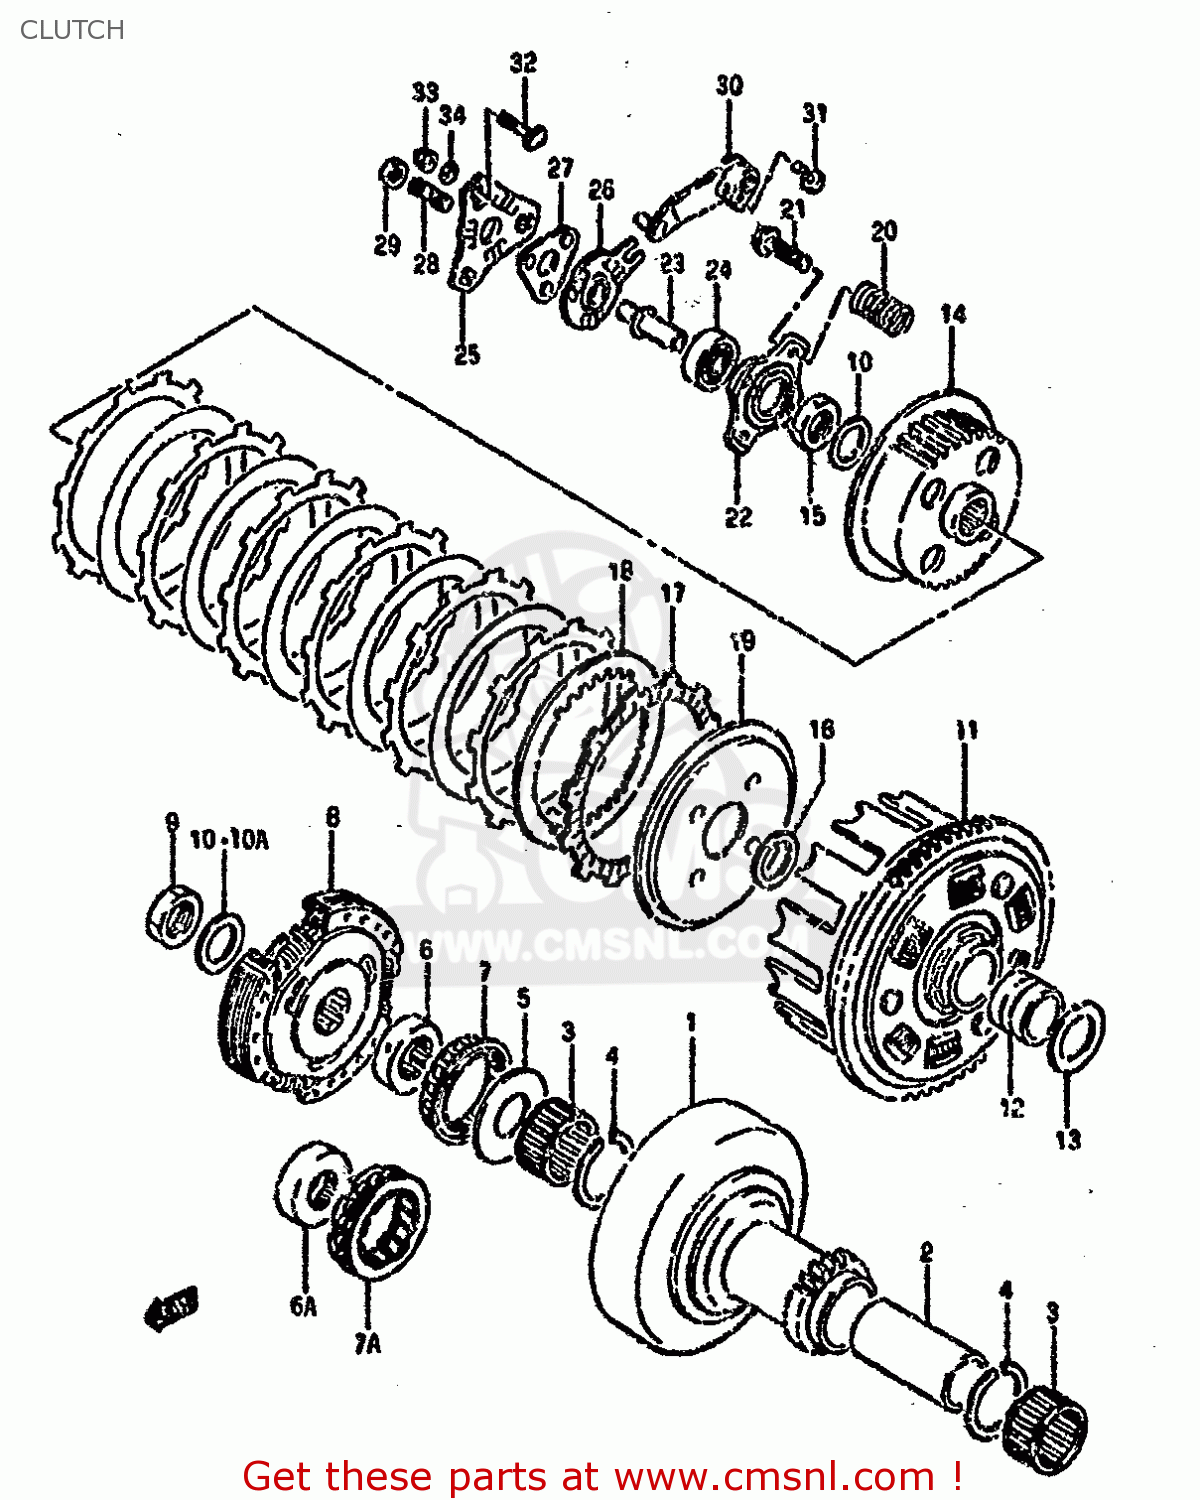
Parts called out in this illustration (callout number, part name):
1	GEAR COMP,PRIMARY DRIVE
2	SPACER
3	ROLLER BEARING (28X32X1
4	CIRCLIP
5	WASHER (22X48X2.5)
6	RACE,ONE WAY CLUTCH INNER
6A	RACE,ONE-WAY CLUTCH IN
7	OVER RUN ONE WAY ASSY,NO.2
7A	CLUTCH ASSY,ONE WAY
8	CLUTCH ASSY,SHOE (NAS)
9	NUT
10	WASHER
10A	WASHER
11	GEAR ASSY,PRI DRIVEN
12	SPACER(22X28X23)
13	WASHER,THRUST
14	HUB,CLUTCH SLEEVE
15	NUT (20MM)
16	WASHER
17	PLATE,CLUTCH DRIVE (NAS)
18	PLATE,DRIVEN(T:1.4)
19	DISC,CLUTCH PRESSURE
20	SPRING
21	BOLT
22	PLATE,RELEASE
23	PIECE,CLUTCH PUSH
24	BEARING
25	GUIDE,BALL
26	BALL GUIDE,CLUTCH RELEASE
27	BALL,CLUTCH RELEASE
28	SCREW(8X19.5)
29	NUT
30	ARM,CLUTCH RELEASE
31	BOLT
32	BOLT
33	NUT
34	GASKET(5.8X13X1.2) (NAS)
